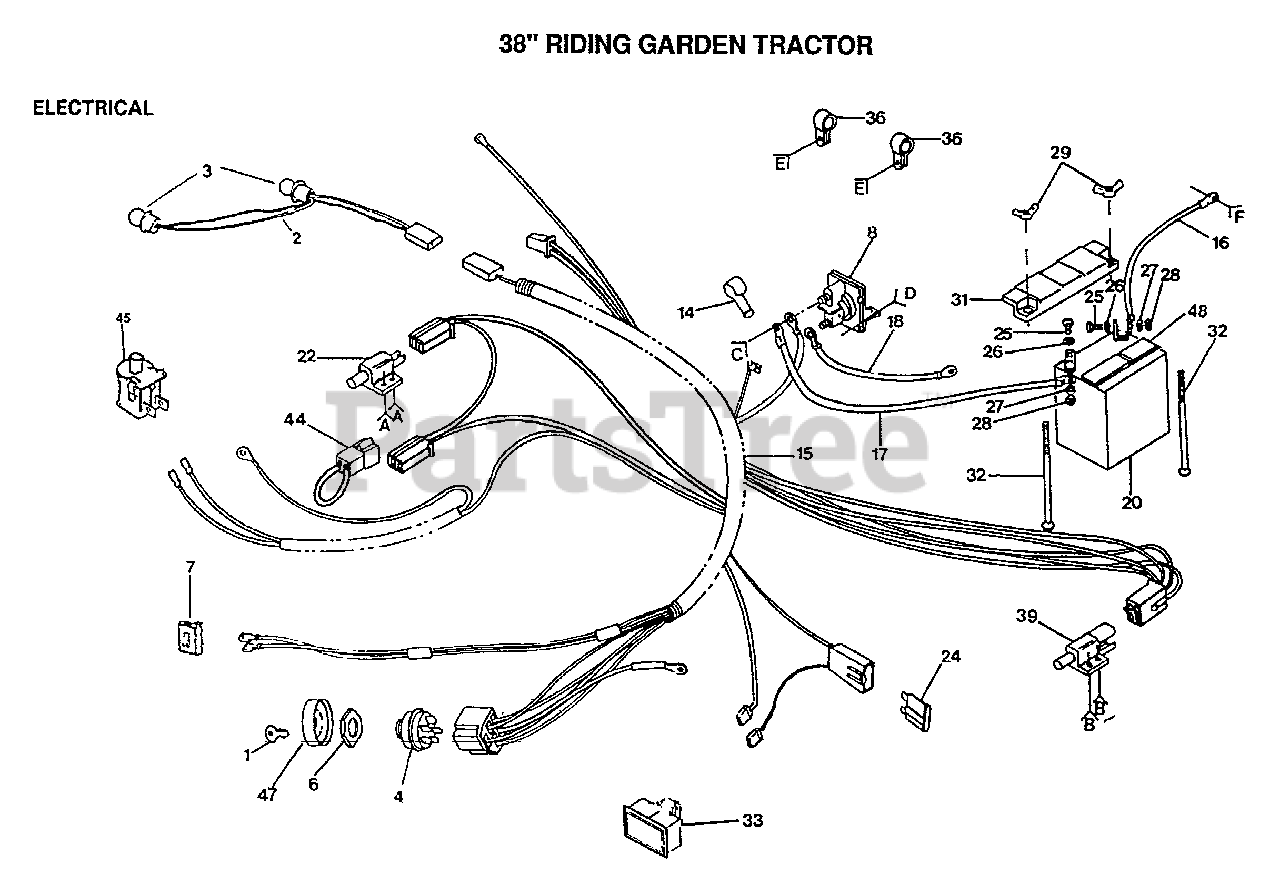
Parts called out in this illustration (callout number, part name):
1	KEY
2	HARNESS T
7	SWITCH LT
15	HARNESS
16	"CABLE T, BATTERY"
17	CABLE LT
18	CABLE T
22	SWITCH-INTER. GT
24	FUSE HYT
25	BOLT LT
26	WASHER
27	LOCKWASHER
32	BOLT
36	CLIPT
39	SWITCH INTERLOCKT
45	SWITCH SEAT
48	"CAP,BATTERY "
